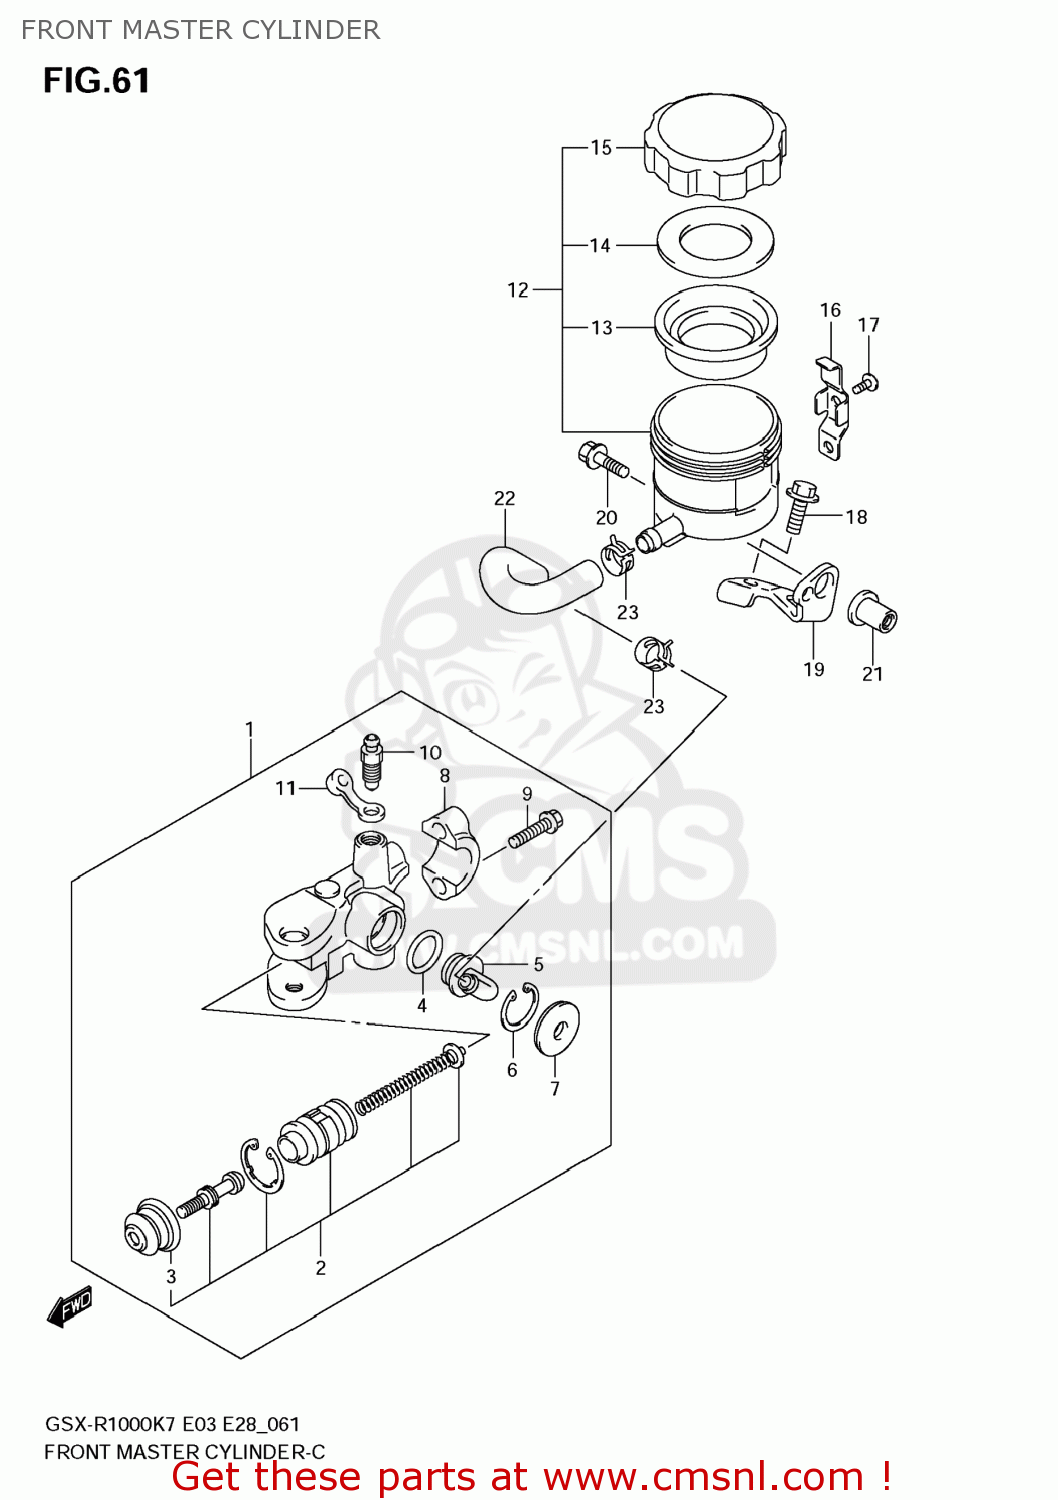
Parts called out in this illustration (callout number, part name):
1	CYLINDER ASSY,
2	PISTON / CUP S
3	BOOT
4	O RING
5	CONNECTOR
6	CIRCLIP
7	COVER,DUST
8	HOLDER
9	BOLT(6X22)
10	BLEEDER
11	CAP,BLEEDER
12	TANK ASSY,RESERVOIR
13	DIAPHRAGM
14	PLATE,DIAPHRAGM
15	CAP
16	PLATE,RESERVOIR TANK CAP
17	SCREW
18	BOLT
19	BRACKET,FR RES
20	BOLT
21	NUT
22	HOSE,FRONT RES
23	CLAMP,RESERVOIR TANK FR
